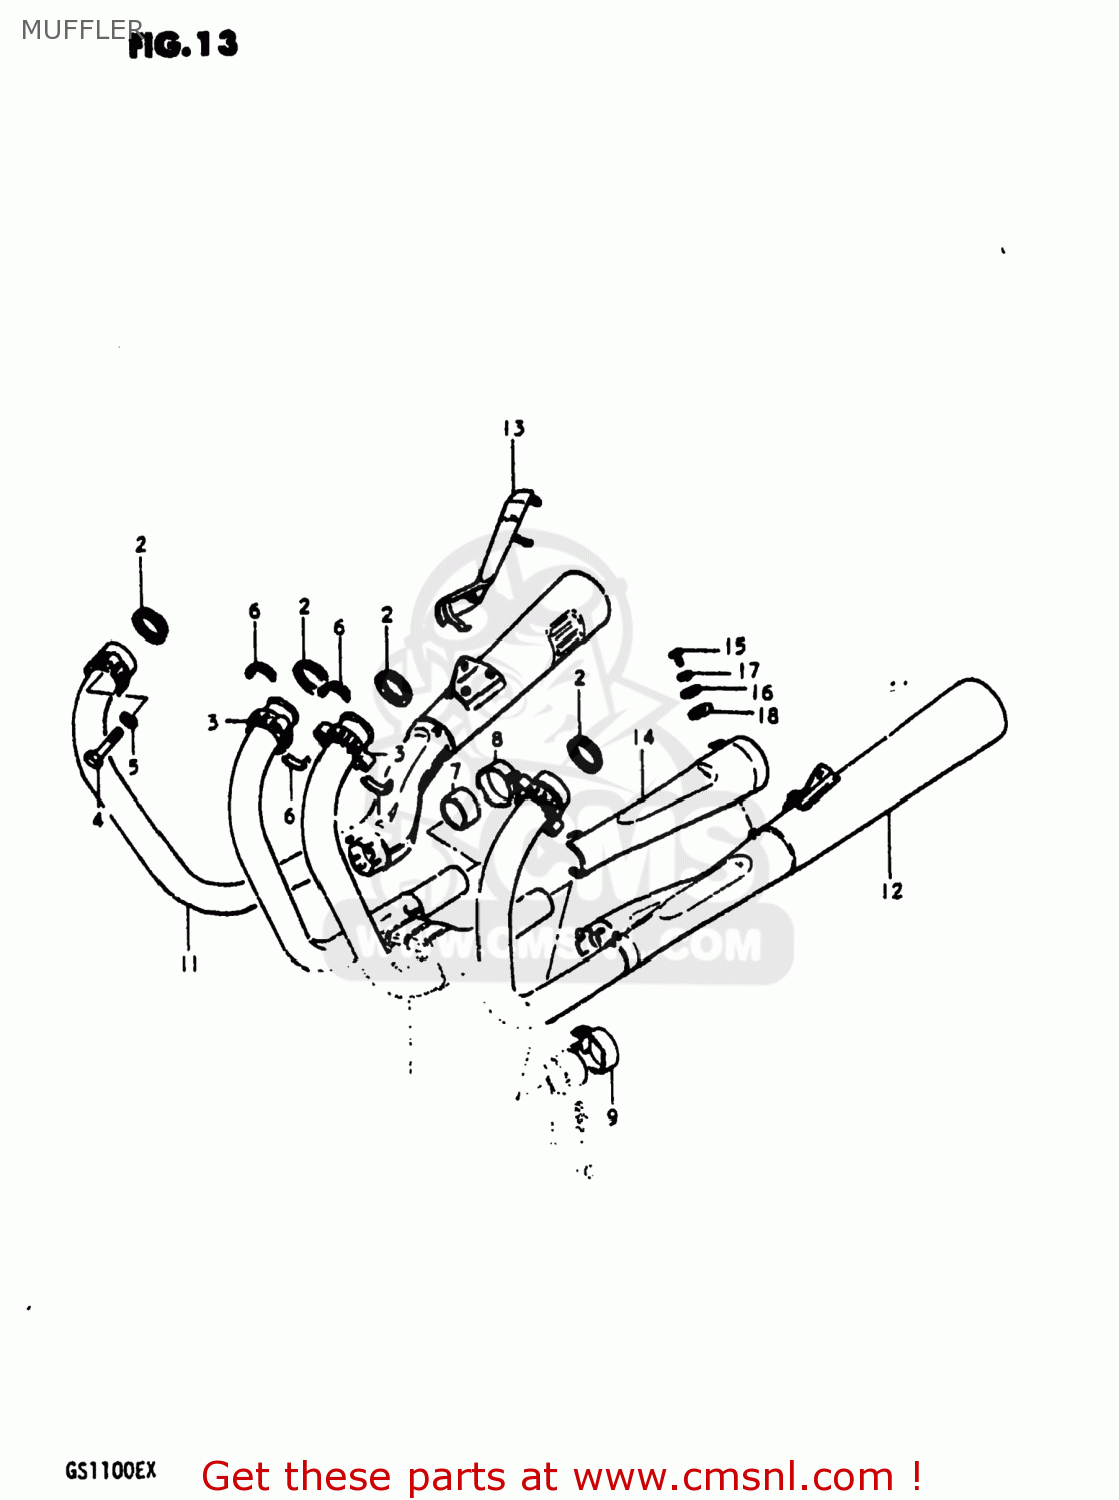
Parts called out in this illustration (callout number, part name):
1	PIPE,EXHAUST,CENTER
2	GASKET,EXHAUST PIPE (NAS)
3	CLAMP,EXHAUST PIPE
4	BOLT
5	LOCK WASHER
6	PLATE,EXHAUST
7	CONNECTOR,MUFFLER
8	CLAMP,MUFFLER CONNECTOR,R
9	CLAMP,MUFFLER CONNECTOR,L
10	BOLT
11	MUFFLER, RH
12	MUFFLER, LH
13	COVER,MUFFLER
14	COVER,MUFFLER
15	SCREW
16	WASHER
17	LOCK WASHER
18	GASKET 6.2X12X1.5 (MCA)
